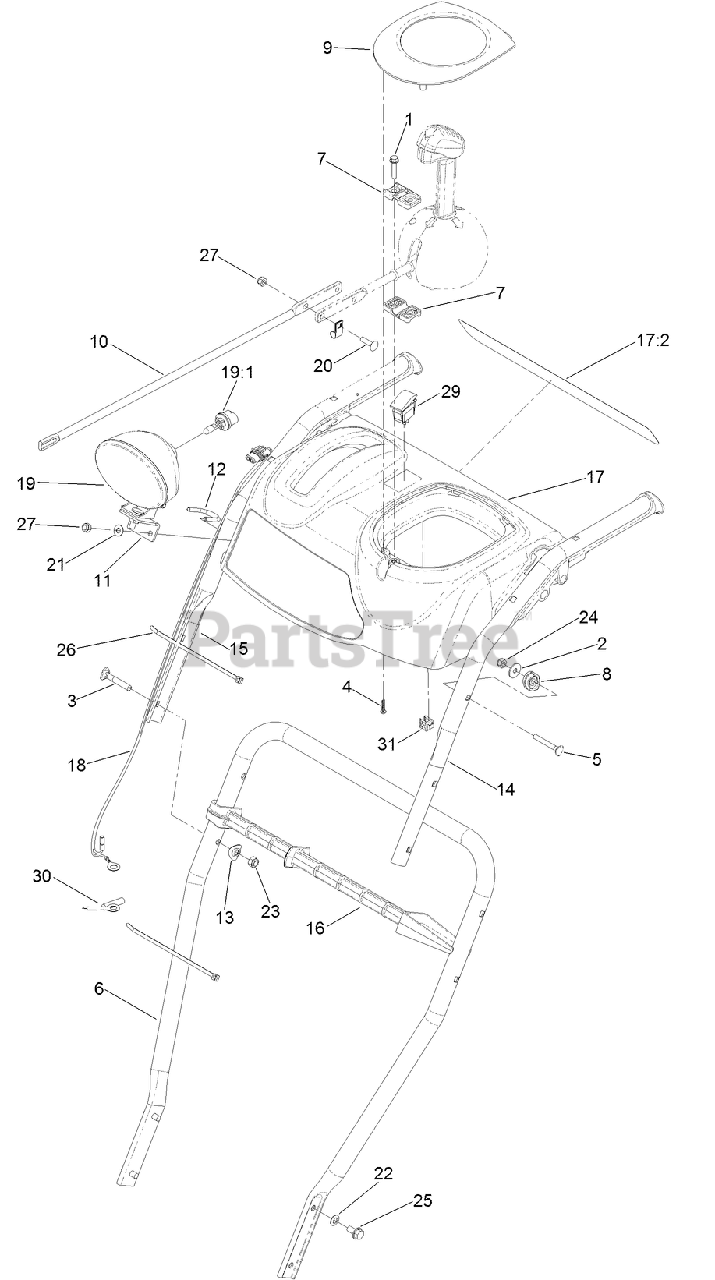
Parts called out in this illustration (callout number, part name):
1	SCREW-PLASTITE
2	WASHER-PLAIN
3	SCREW-HANDLE
4	SCREW-PPH
5	SCREW
6	HANDLE-LOWER
7	SUPPORT-ROD
8	CLAMP-CABLE
9	COVER-PANEL, CONTROL
10	ROD-CHUTE, FRONT
11	BRACKET-LIGHT
13	WASHER
14	HANDLE-UPPER, LH
15	HANDLE-UPPER, RH
16	STICK-CLEANOUT
17	CONTROL PANEL ASM
17:2	DECAL-CONTROL
18	HARNESS-WIRE, HEATED GRIPS
19	HEADLAMP ASM
19:1	LAMP-12 VOLT
20	SCREW-CARR
21	WASHER-FLAT
22	WASHER-BELLEVILLE
23	NUT-LOCK, NI
24	NUT-LOCK, NI
25	SCREW-HWHTF
26	TIE-CABLE
27	NUT-LOCK, NI
29	SWITCH-ROCKER, OFF-NONE-ON
30	HARNESS-WIRE, GROUND JUMPER
31	CLIP-EDGE
